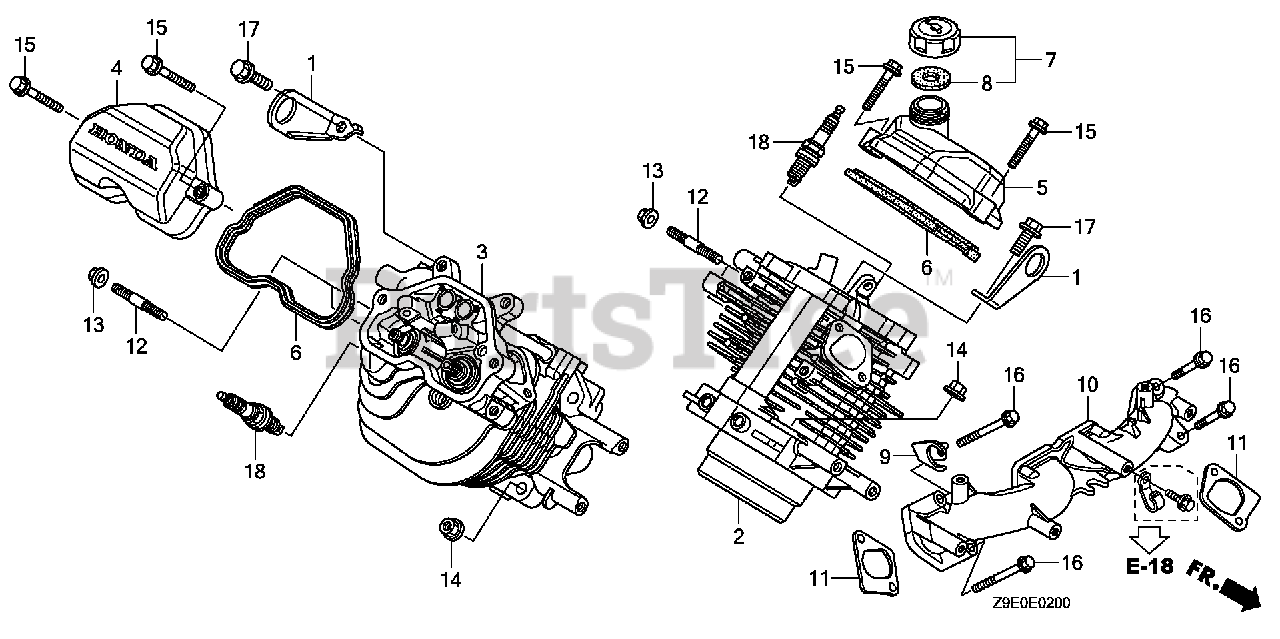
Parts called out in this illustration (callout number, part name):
1	HANGER, ENGINE
2	CYLINDER HEAD (#1)
2	CYLINDER HEAD
3	CYLINDER HEAD (#2)
3	CYLINDER HEAD
4	COVER, CYLINDER HEAD
5	COVER, CYLINDER HEAD
6	GASKET, HEAD COVER
7	CAP ASSY., OIL FILLER
8	GASKET, OIL FILLER CAP
9	STAY, FUEL TUBE GROMMET
10	MANIFOLD, IN.
11	GASKET, IN. MANIFOLD
12	BOLT, STUD (8X22)
13	NUT, FLANGE (8MM)
14	NUT, FLANGE (10MM)
15	BOLT, FLANGE (6X30)
16	BOLT, FLANGE (8X55)
16	BOLT, FLANGE (6X50)
17	BOLT, FLANGE (8X16) Use from Engine SN 1000016.
18	SPARK PLUG (ZFR5F)
